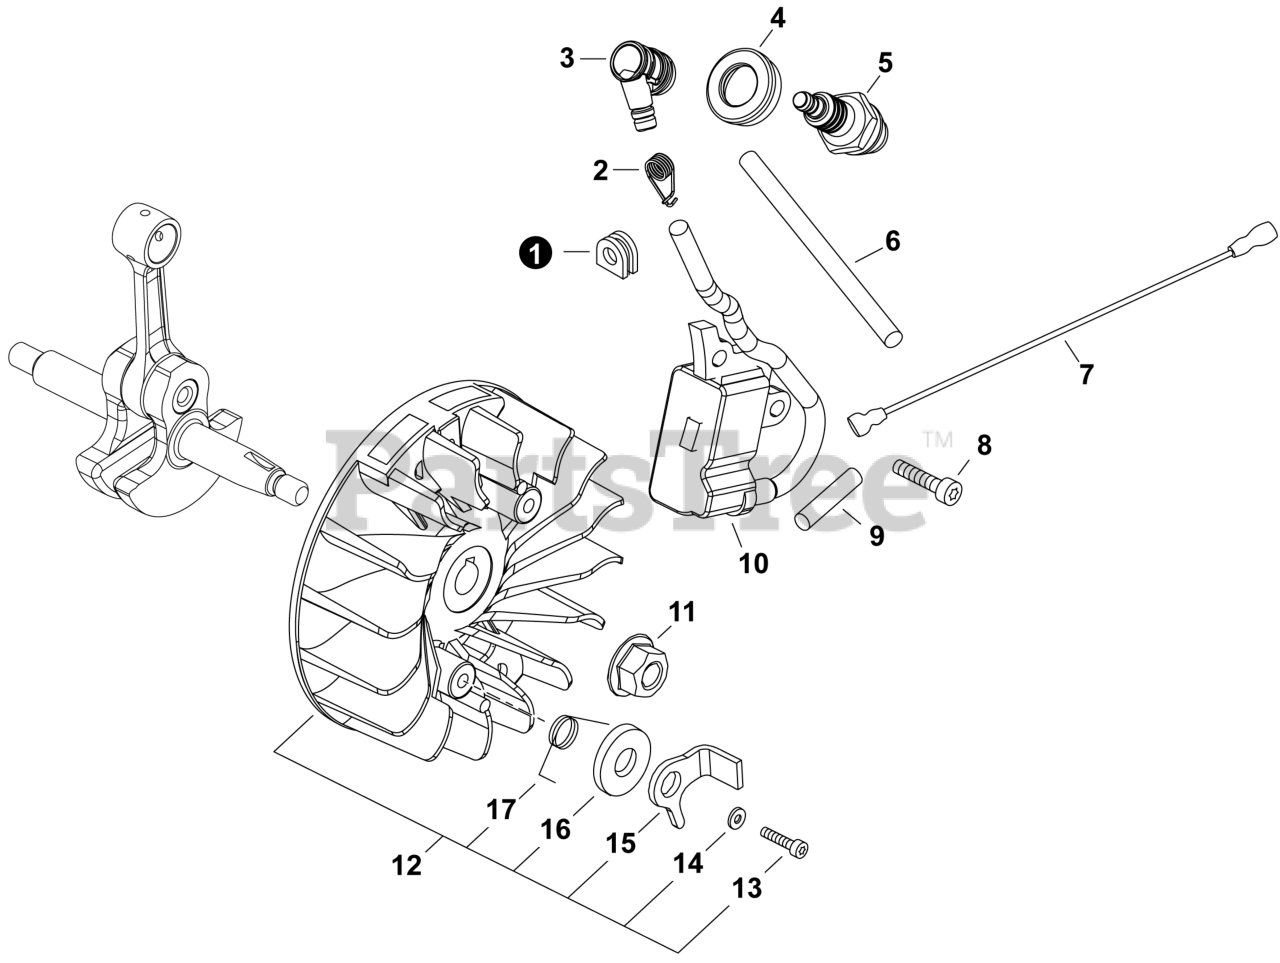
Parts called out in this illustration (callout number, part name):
2	TERMINAL, SPARK PLUG
3	CAP, SPARK PLUG
4	SEAL, SPARK PLUG
5	SPARK PLUG - BPMR8Y
6	TUBE, INSULATOR
7	LEAD - IGNITION
8	BOLT, TORX 5x16
9	TUBE, INSULATOR
10	COIL, IGNITION
11	NUT, FLANGE M8x1.25
12	FLYWHEEL KIT
13	BOLT, TORX 5x12
16	WASHER 5.5x16x0.8
17	SPRING, TORSION
